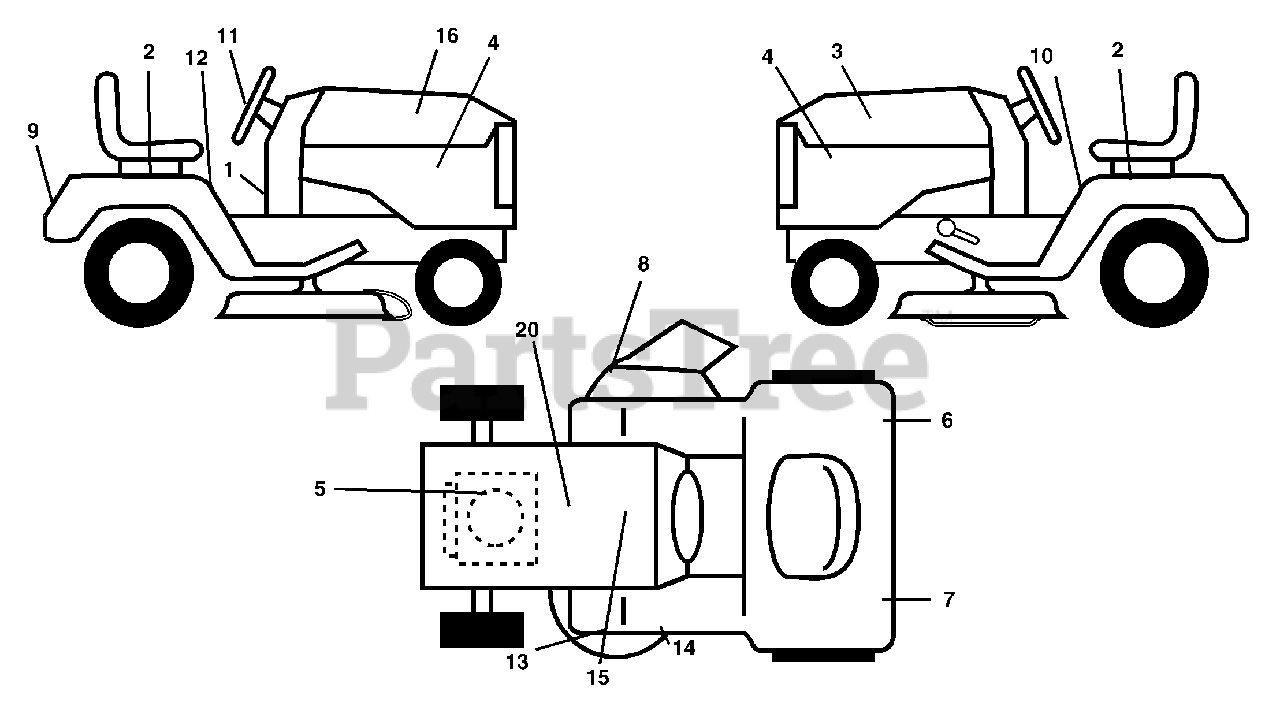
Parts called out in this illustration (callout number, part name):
1	Decal Dash
2	Decal Fender Auto
3	Decal Hood LH
4	Decal Side Panel
5	Decal HP Engine
6	Decal Reflector Rh
7	Decal Reflector Lh
8	Decal Warning Mower
9	Decal Fender Logo
10	Decal Fender Danger E/F
11	Decal Ins Strg Whl
12	Decal Fender Oper Cruise
13	Decal Deck Caution
14	Decal V-Belt Schematic
15	Decal Replace
16	Decal Hood Rh
20	Decal Bat Dan/Psn
